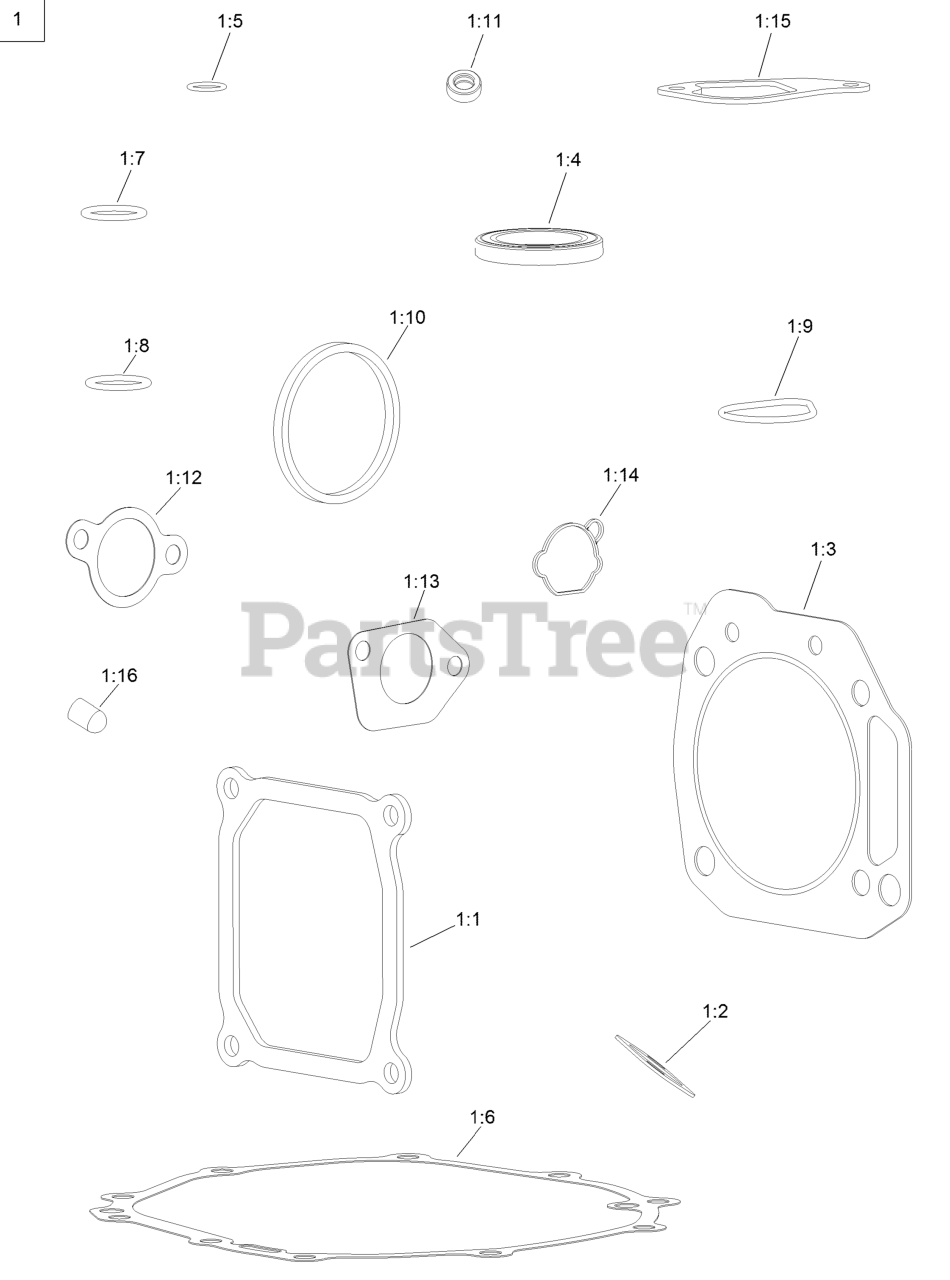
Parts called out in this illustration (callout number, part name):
1	GASKET AND SEAL KIT
1:1	GASKET-COVER, VALVE
1:2	GASKET-EXHAUST
1:3	GASKET-CYCLINDER
1:4	SEAL-OIL
1:6	GASKET-CRANKCASE
1:9	SEAL-PUMP, OIL
1:10	SEAL-ADAPTOR, OIL
1:11	SEAL-OIL
1:12	GASKET-CARBURETOR
1:13	GASKET-CARBURETOR
1:14	GASKET-CARBURETOR
1:15	GASKET-BREATHER
1:16	CAP-SEAL
